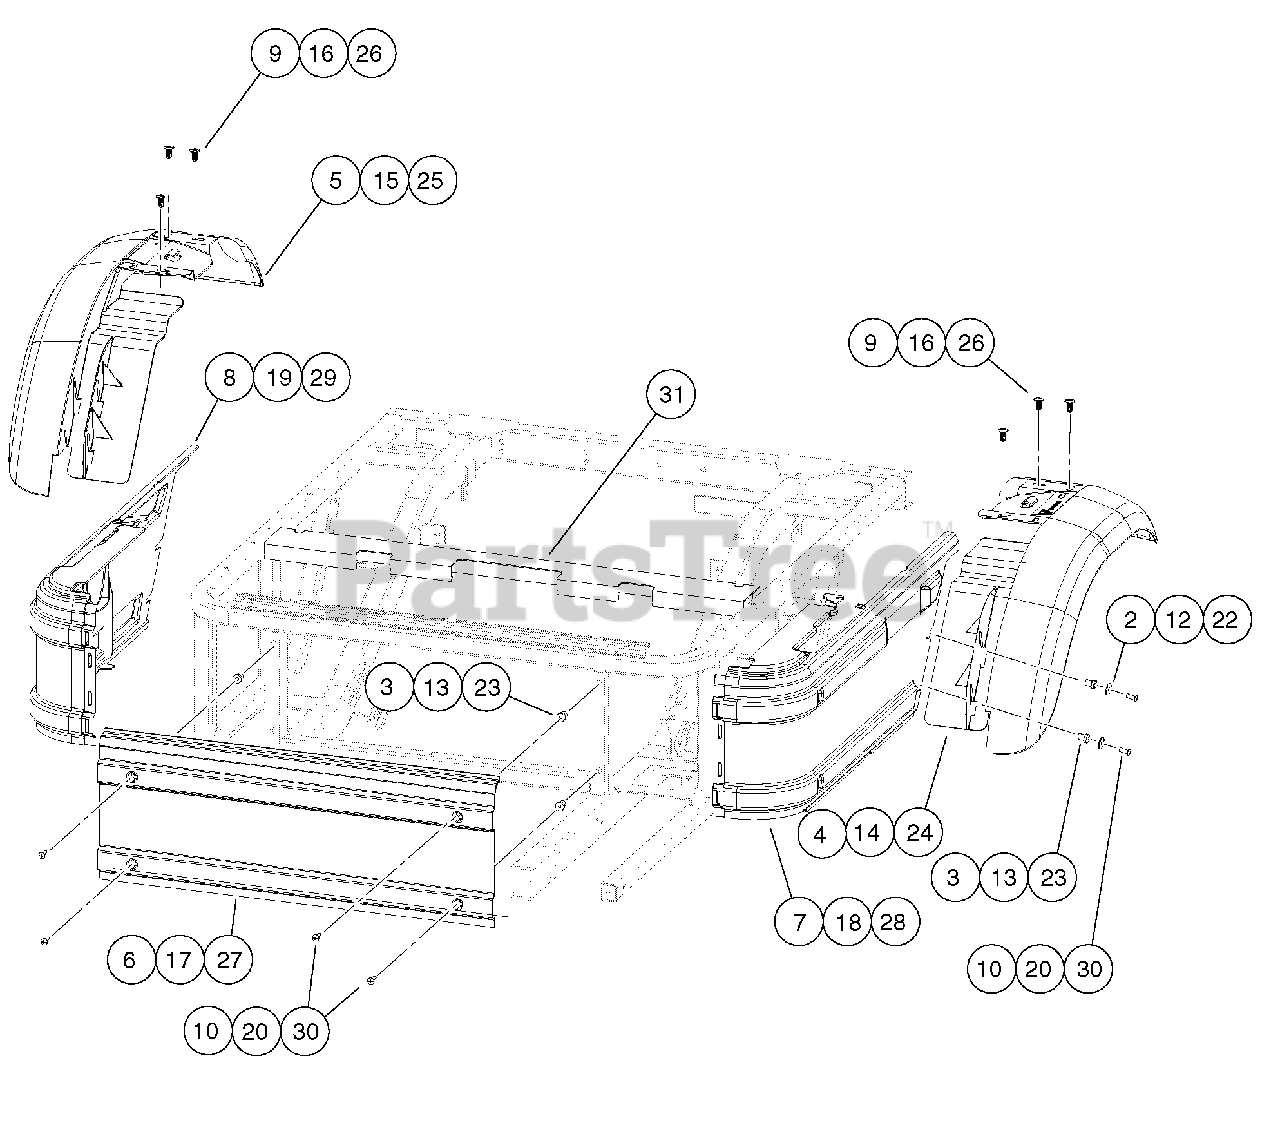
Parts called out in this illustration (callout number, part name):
1	Instl, Panels, Fenders, Blk
2	Washer, 1/4" Type B Flat
3	Well Nut 1/4-20
4	Left Rear Fender
5	Right Rear Fender
6	Panel, Front, Kick
7	Panel, Side, Molded, Driver
8	Panel, Side, Molded, Passenger
9	Screw, Tuflok, 10mm
10	Screw, 1/4-20 X 1.0 Truss-Head Machine
11	Instl, Panels, Fenders, Rthwd
12	Washer, 1/4" Type B Flat
13	Well Nut 1/4-20
14	Left Rear Fender
15	Right Rear Fender
16	Screw, Tuflok, 10mm
17	Panel, Front, Kick, Rthwhd
18	Pnl, Side, Mld, Drv, Rthwhd
19	Pnl, Side, Mld, Pass, Rthwhd
20	Screw, 1/4-20 X 1.0 Truss-Head Machine
21	Instl, Panels, Fenders, Moff
22	Washer, 1/4" Type B Flat
23	Well Nut 1/4-20
24	Left Rear Fender
25	Right Rear Fender
26	Screw, Tuflok, 10mm
27	Panel, Front, Kick, Moff
28	Pnl, Side, Mld, Drv, Moff
29	Pnl, Side, Mld, Pass, Moff
30	Screw, 1/4-20 X 1.0 Truss-Head Machine
31	Closeout, Extrusion
